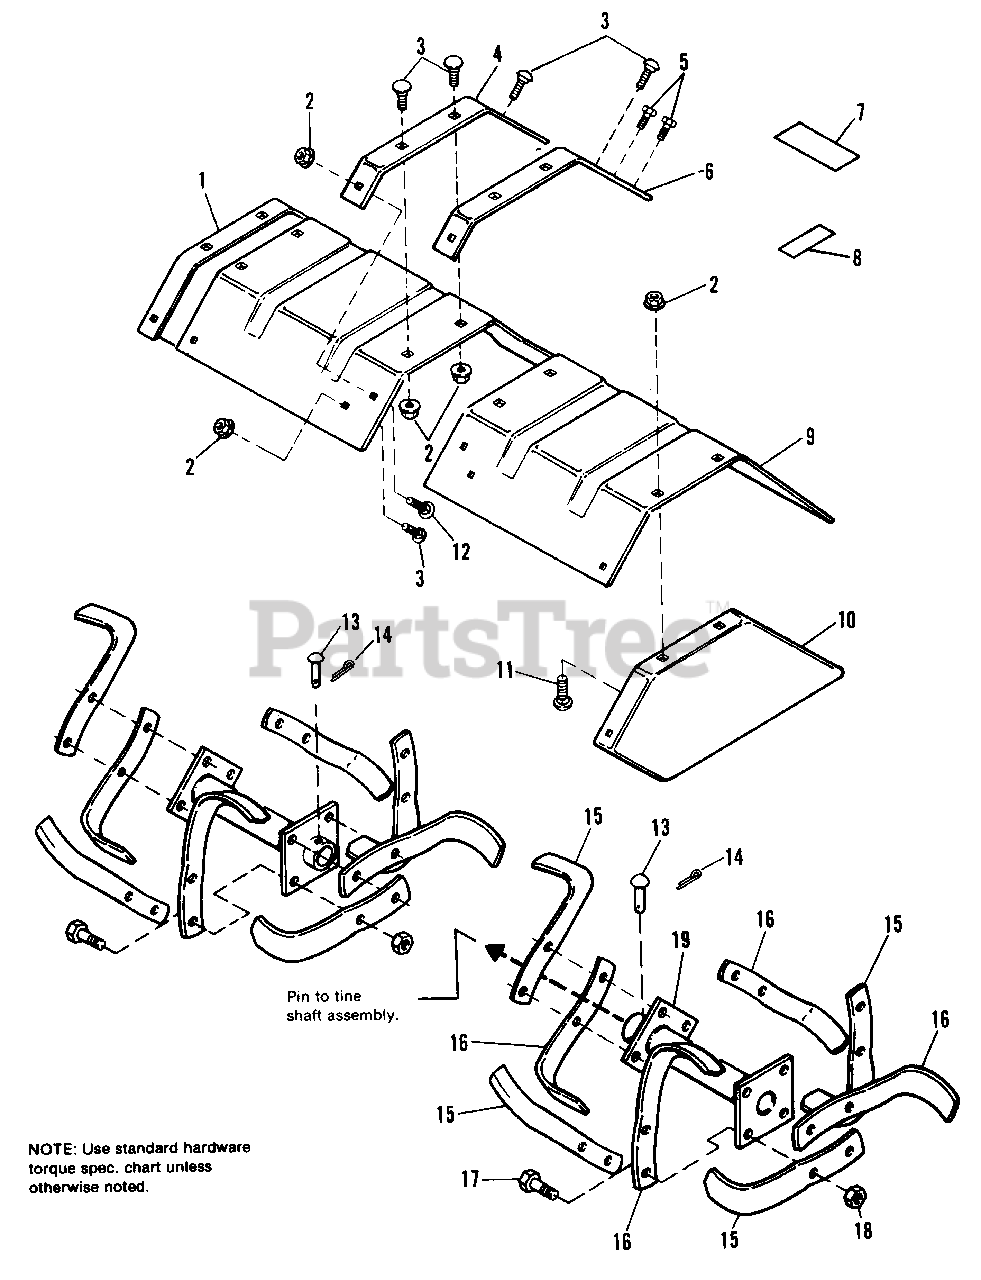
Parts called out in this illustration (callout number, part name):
1	PLATE END, Deflector, R.H.
2	NUT, Hex, Flange, 5/16-18
3	BOLT, Carriage, 5/16-18 x 5/8
4	BAR, Reinforcement, R.H.
5	SCREW, Taptite, 5/16-18 x 3/4
6	BAR, Reinforcement, L.H.
7	DECAL, Safety
8	DECAL, Drive Control
9	DEFLECTOR
10	PLATE END, Deflector, L.H.
11	BOLT, Carriage, 5/16-18 x 1/2
12	BOLT, Carriage, 5/16-18 x 1
13	PIN
14	PIN, Cotter, 1/8 x 3/4
15	TINE BLADE, L.H.
16	TINE BLADE, R.H.
17	CAPSCREW, Hex, 7/16-20 x 1-1/4
18	LOCKNUT, Hex, 7/16-20
19	HUB & PLATE ASSY., Tine
